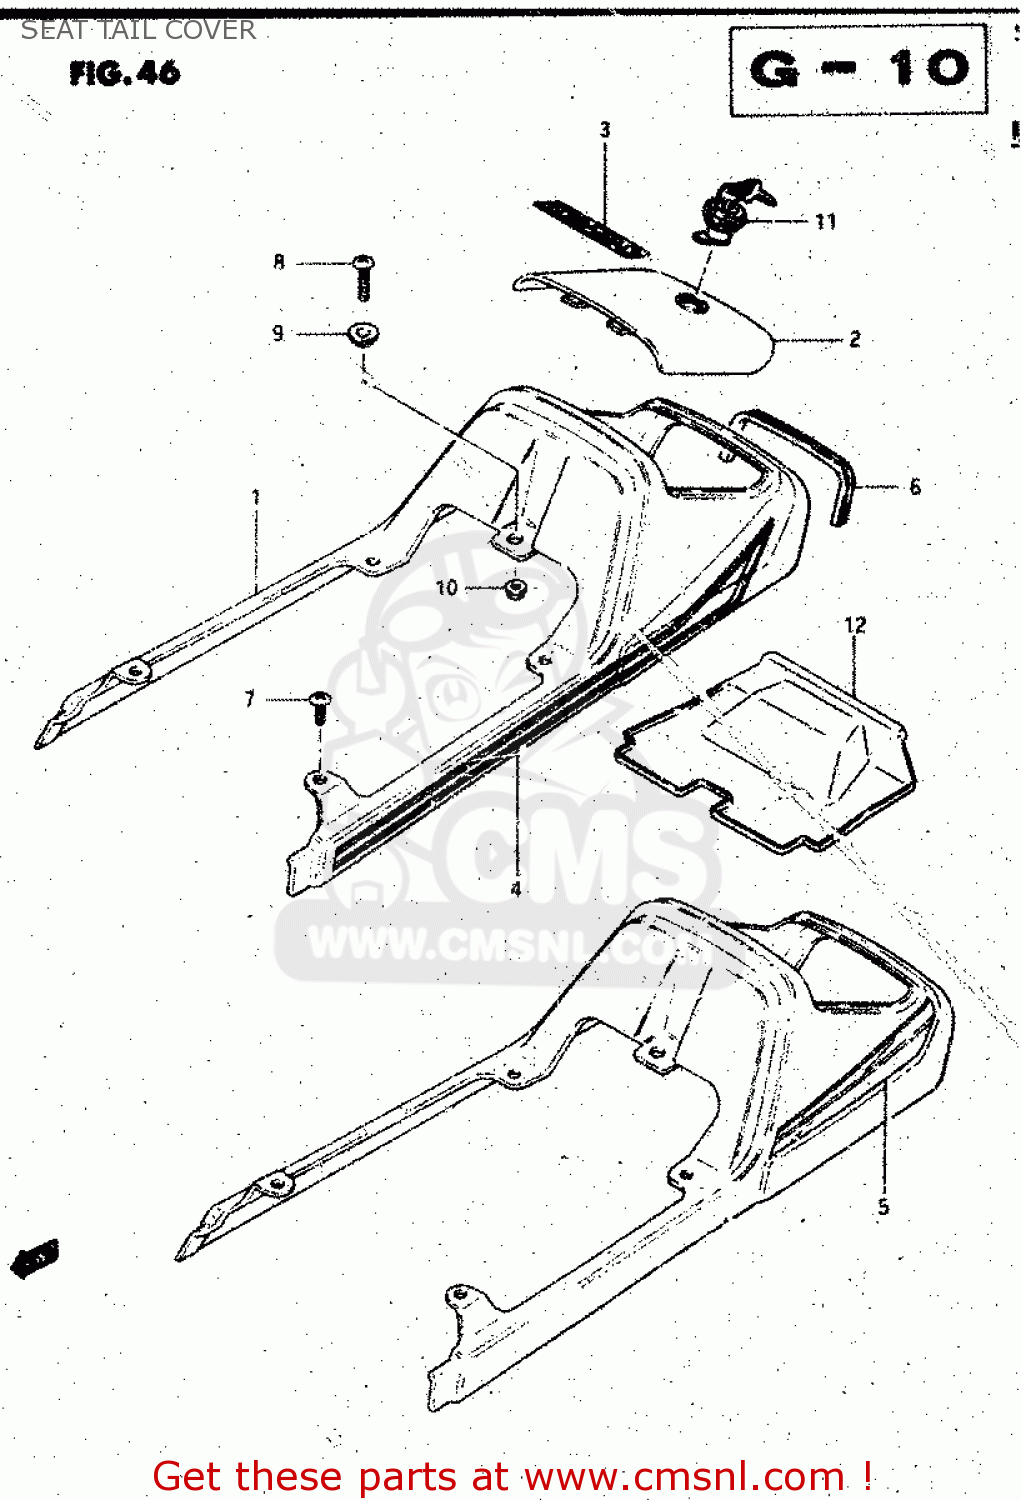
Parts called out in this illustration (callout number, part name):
1	COVER, SEAT TAIL (RED)
2	FLAP,SEAT TAIL COVER
3	EMBLEM (GOLD/BLACK)
4	TAPE SET, SEAT TAIL COVER
5	TAPE SET, SEAT TAIL COVER
6	MOLE,SEAT TAIL COVER
7	SCREW 6X12
8	SCREW
9	WASHER
10	NUT
11	LOCK SET,TAIL COVER
12	BOTTOM,SEAT TAIL COVER
